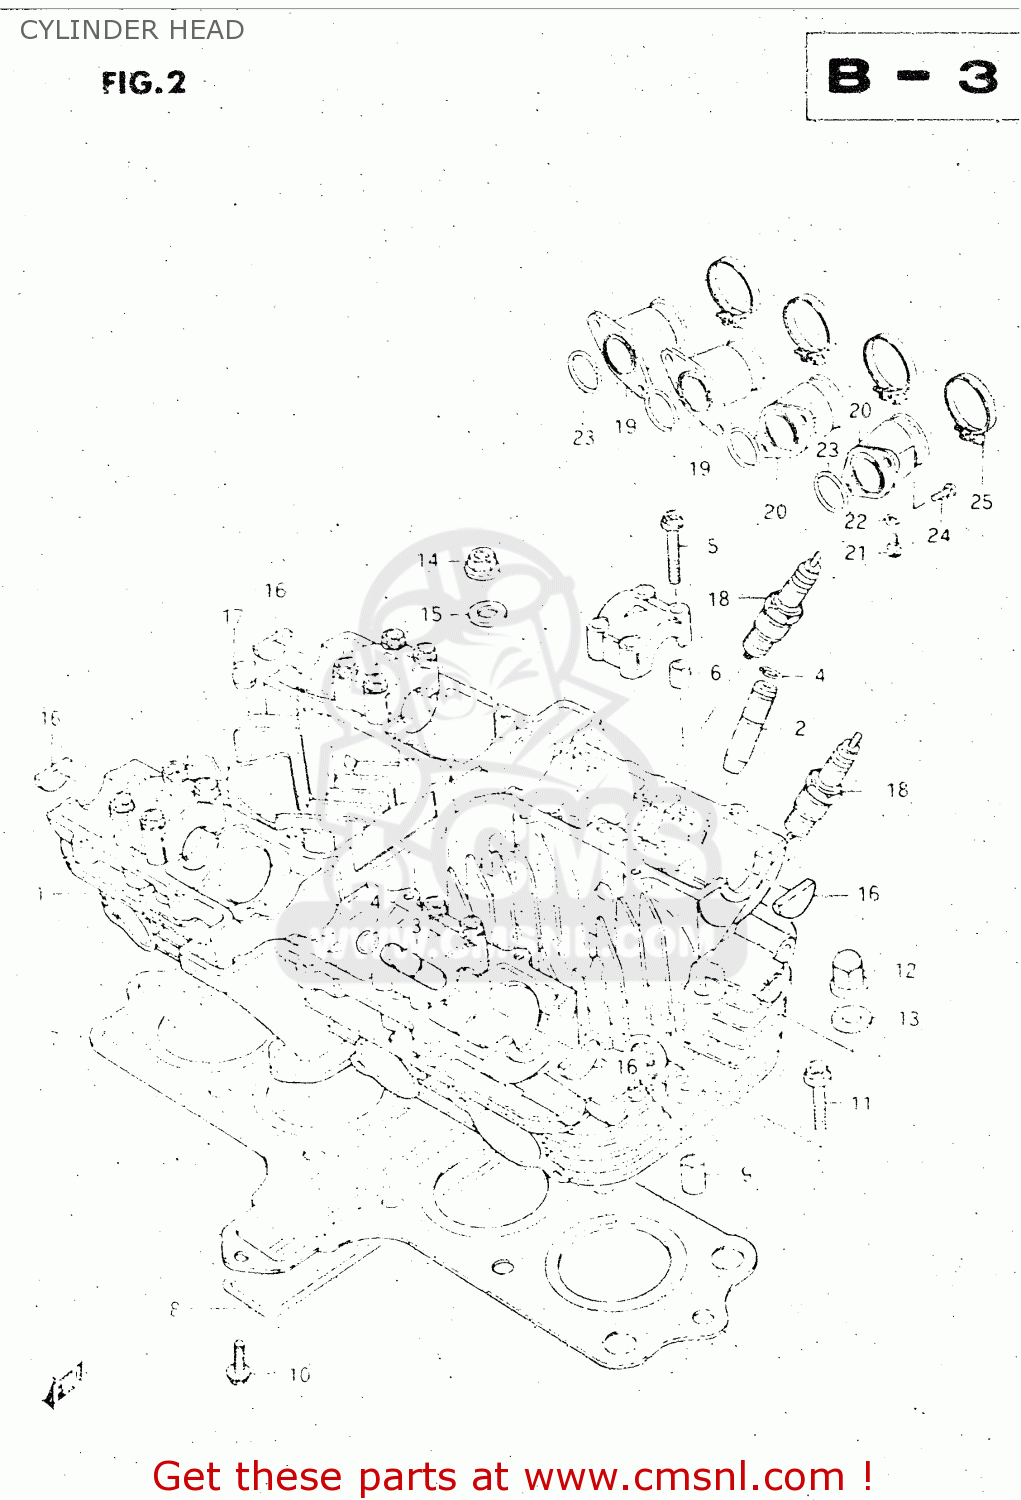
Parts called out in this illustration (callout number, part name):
1	CYLINDER HEAD ASSY
2	GUIDE,INTAKE VALVE
3	GUIDE,EXHAUST VALVE
4	RING,SNAP
5	BOLT(6X39)
6	PIN(6.2X8X11)
7	GASKET
8	O RING(D:3,ID:26X157)
9	PIN
10	BOLT
11	BOLT,UNDER
12	NUT
13	GASKET (NAS)
14	NUT
15	WASHER(8.5X19X2.3)
16	PLUG
17	PAD
18	SPARK PLUG DR8ES-L
19	PIPE,INTAKE,R
20	PIPE,INTAKE,L
21	BOLT
22	WASHER
23	O-RING
24	SCREW
25	CLAMP
